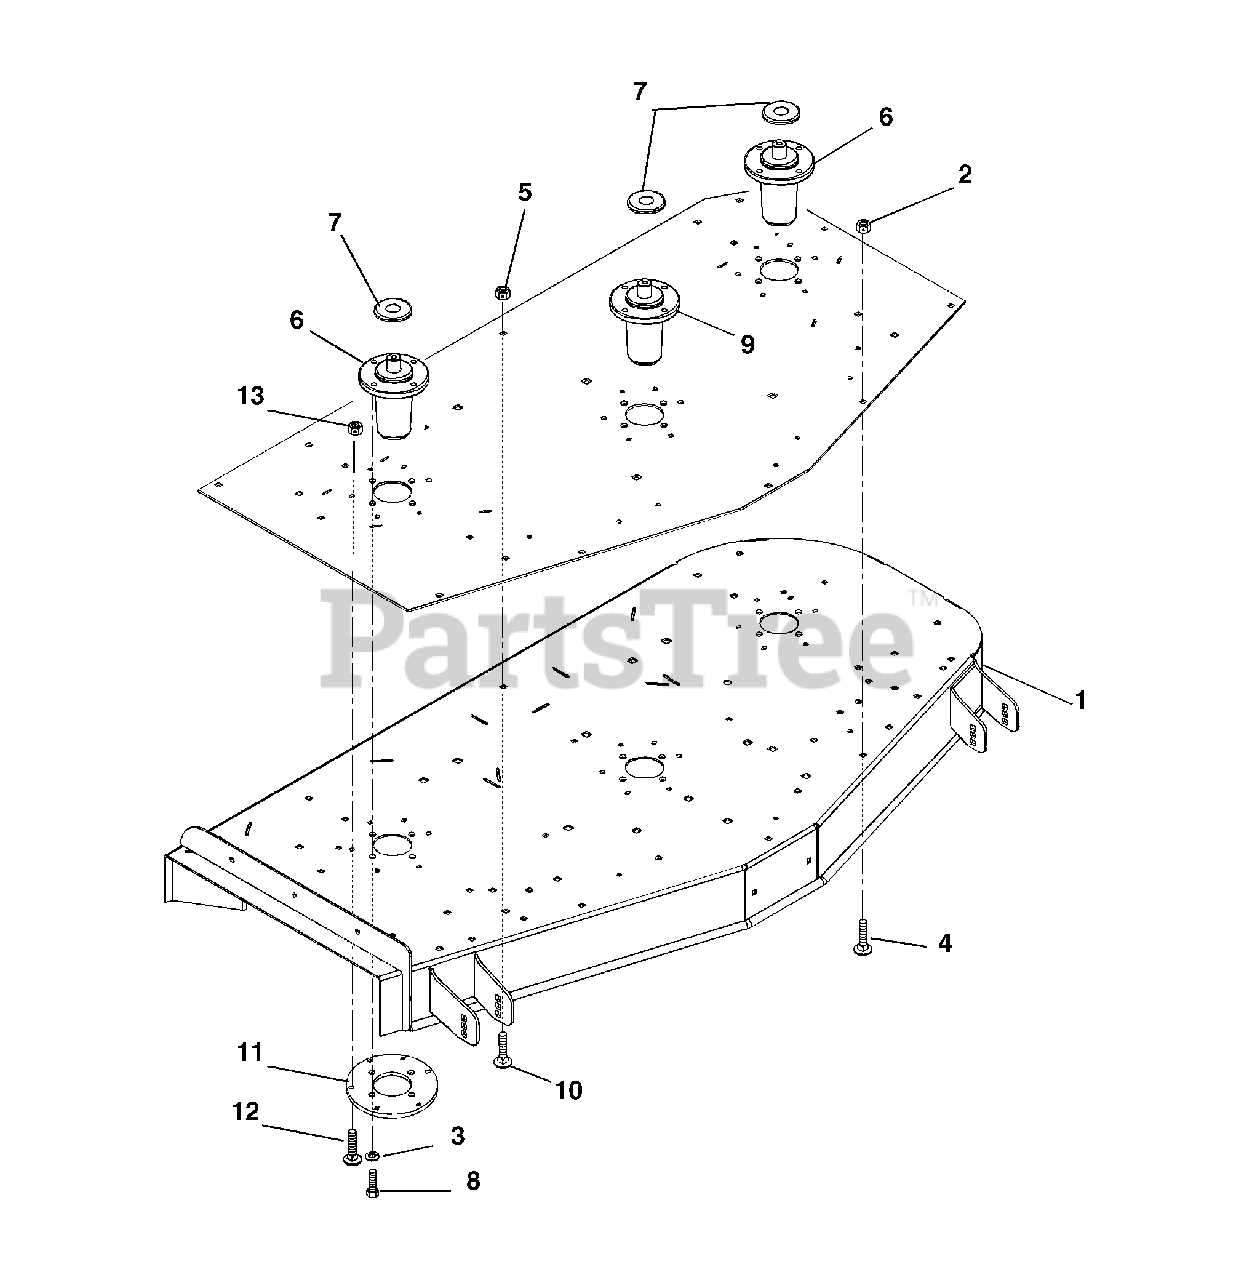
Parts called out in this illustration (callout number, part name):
1	Weldment, 72" Deck (Side Discharge)
2	Plate, 72" Reinforcment
3	Washer-Locking .38 x .094
4	Bolt-Round Head Square Neck .38-16 x 2.75 Grade 5
5	Nut-Locking-Nylon .38-16
6	Assembly, Spindle L-Hub
7	Slinger-Dust
8	Bolt-Hex .38-16 x 1.00 Grade 5
9	Assembly, Spindle
10	Bolt-Round Head Square Neck .38-16 x 1.00 Grade 2
11	Plate, Spindle Reinforcement
12	Bolt-Round Head Square Neck .38-16 x 1.00 Grade 5
13	Nut-Locking-Center .38-16
